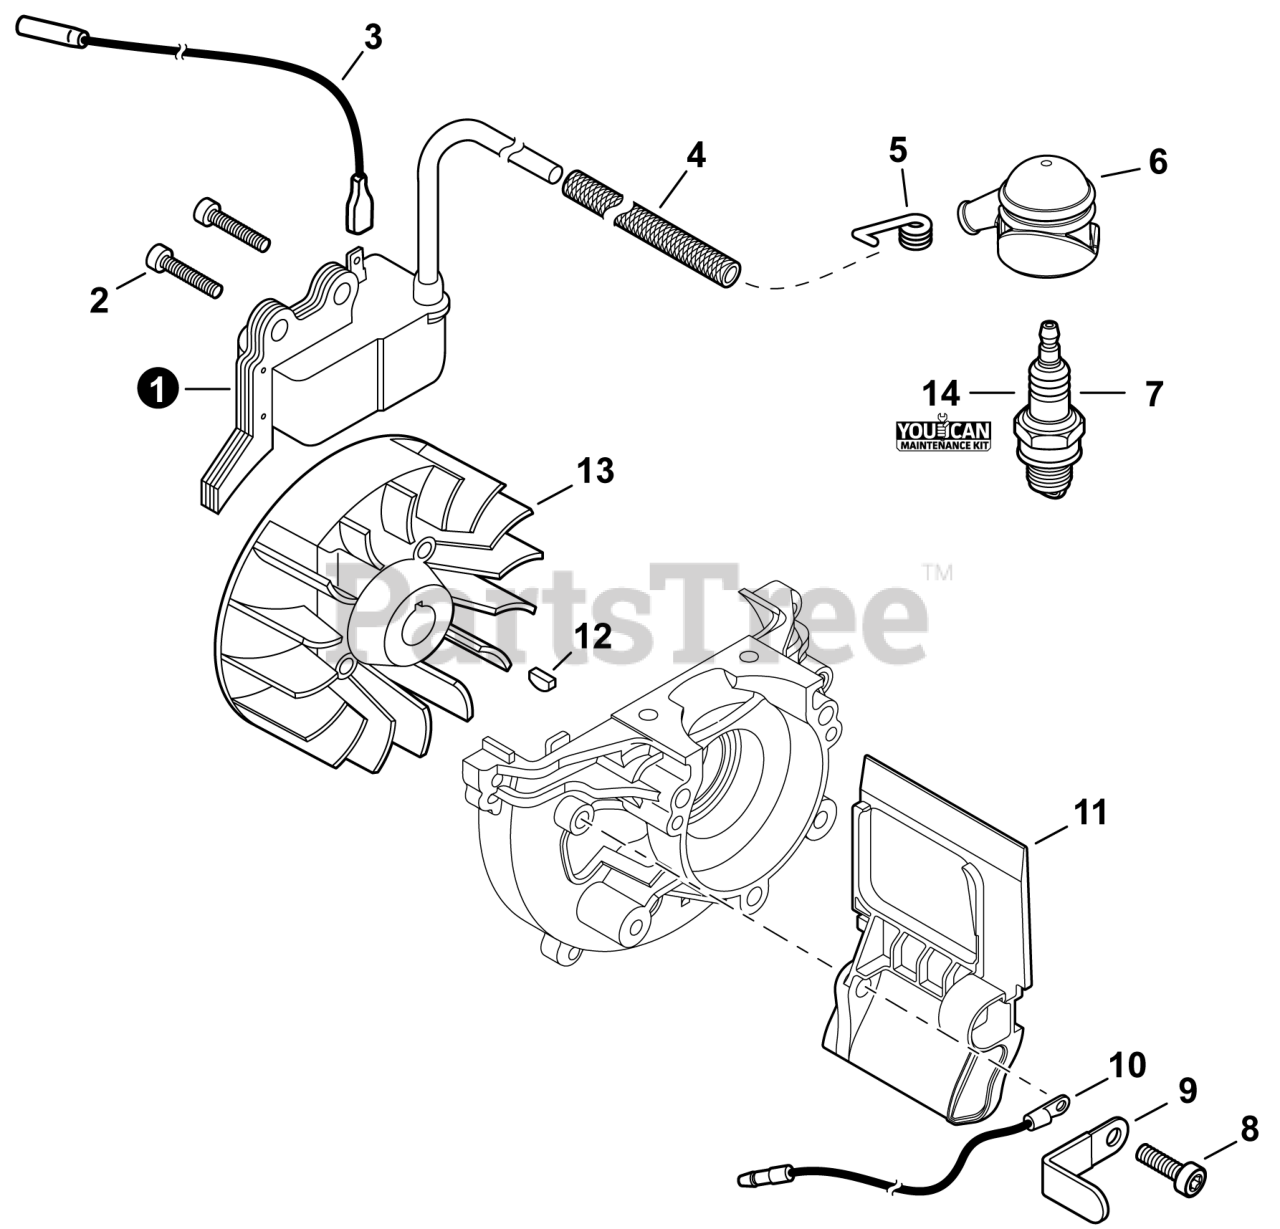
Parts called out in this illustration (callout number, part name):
1	COIL, IGNITION
2	BOLT, TORX 4x20
3	LEAD - IGNITION L= 210
4	TUBE, INSULATOR
5	TERMINAL, SPARK PLUG
6	CAP, SPARK PLUG
7	SPARK PLUG - BPM8Y
8	BOLT, TORX 5x12
10	LEAD - GROUND L= 115
11	PLATE, INSULATOR
12	KEY, WOODRUFF
13	FLYWHEEL
14	TUNE-UP KIT - YOUCANT
